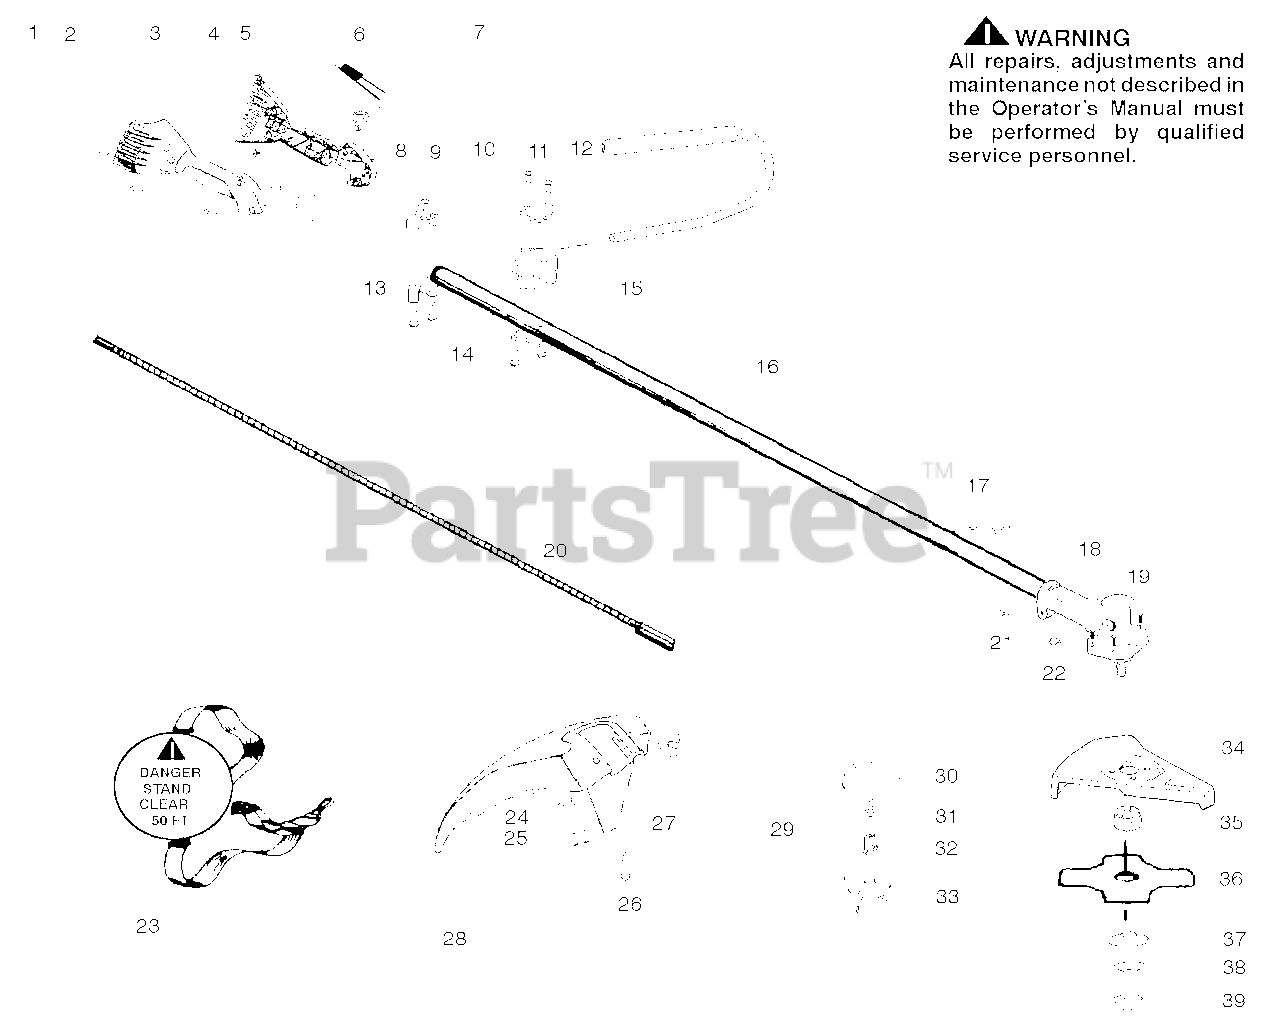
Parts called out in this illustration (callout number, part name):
1	Screw-alignment
3	Hsg.-Throttle-right
4	Screw-Cable Ret.
5	Hsg.-Throttle-left
6	Assy-Wire
7	Kit-Switch
8	Trigger-Throttle
9	Clamp-Harness (upper)
10	Clamp-Bracket
12	Kit-Handlebar Assy.
13	Clamp-Harness (lower)
15	Clamp-Handlebar
16	Kit-Shaft Assy.
17	Bracket-Shield
20	Shaft-Flex
23	Shoulder Strap
24	Limiter-Line
27	Wingnut
28	Kit-Shield Assy.
29	Accy-Cutting Head
30	Assy-Hub
32	Retainer
33	Accy-Wound Spool
34	Kit-Metal Shield
35	Dust cup
36	Accy.-Weed Blade
38	Washer-Belleville
39	Nut-Flange
